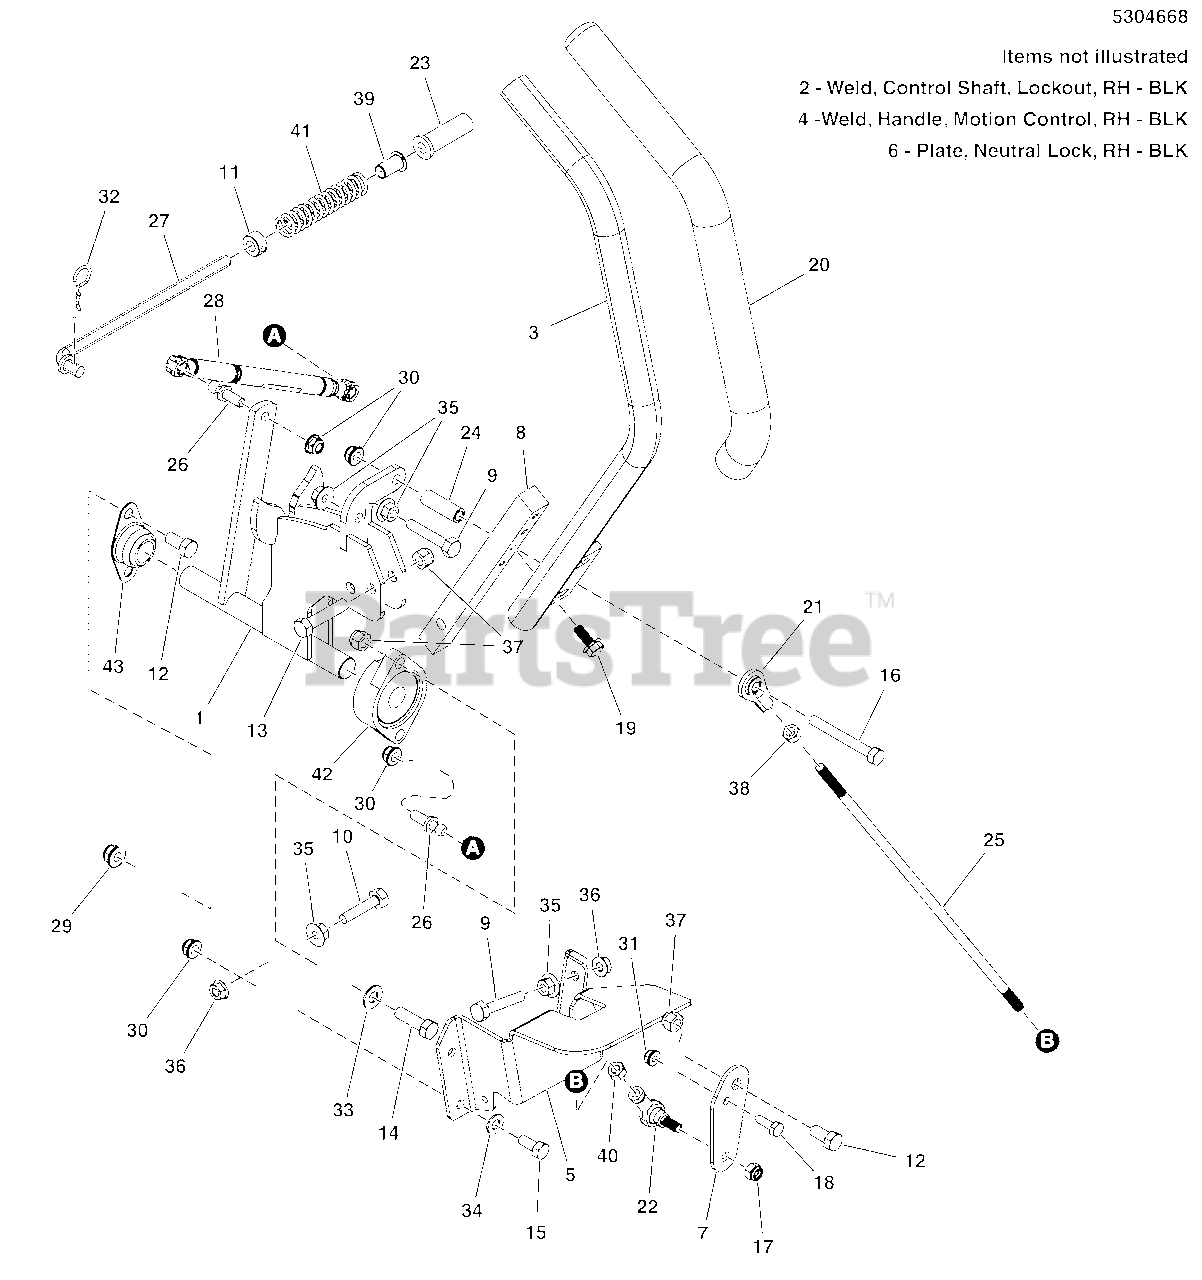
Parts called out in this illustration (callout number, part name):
1	WELD, CONTROL SHAFT, LOCKOUT, LH - BLK
2	WELD, CONTROL SHAFT, LOCKOUT, RH - BLK
3	WELD,HANDLE MOTION CNTRL-19.0,1.0-LH-BLK
4	WELD,HANDLE MOTION CNTRL-19.0,1.0-RH-BLK
5	PLATE, NEUTRAL LOCK, LH - BLK
6	PLATE, NEUTRAL LOCK, RH - BLK
7	PLATE, SPEED CONTROL - BLK
8	MOUNT, CONTROL ARM - BLK
9	BOLT, 5/16-18 X 1-3/4 TFL, GD5 YZ
10	BOLT- 5/16-18 X 1-1/2 GD5 TFL
11	COLLAR, 3/8" Set
12	BOLT, 3/8-16 X 3/4" GD5 CZ
13	BOLT, 3/8-16 X 1-3/4" GD5 CZ
14	BOLT, 3/8-16 X 1-1/4" GD5 CZ
15	BOLT, 5/16-18 X 3/4 GD5
16	BOLT, 5/16-18 X 2-3/4, GD 5, YZ
17	NUT, Hex, Nylon Lock, 5/16-24
18	BOLT, 1/4"-20 X 3/4" GD5 YZ
19	SCREW, 5/16-18X0.750, GR5, WHIZ-LOCK, ZC
20	GRIP, FOAM, 1" ID, 16" LONG
21	BALL JOINT 5/16-24 RH FEMALE STAMPED STL
22	BALL JOINT, 5/16-24 LH FEMALE W/STUD, BR
23	FLANGED BUSHING, 3/8IDX.63ODX.8125FL
24	SPACER, .33 X .50 X 1.50, YZ
25	ROD, HYDRO CONTROL, OUTFRONT
26	10MM BALL STUD, 5/16-18 X 3/4 THDS
27	ROD, NEUTRAL RETURN, CZ
28	DAMPENER, CONTROL,#(P6709/P3610)
29	NUT, 3/8 - 16 HEX NYLOCK FLANGE
30	NUT, 5/16-18 HEX NYLOCK FLANGE NUT
31	NUT, 1/4-20 Hex Nylock Flange
32	3/32 X 1-5/8 HAIR PIN CLIP
33	WASHER, 3/8 SAE
34	WASHER, 5/16" SAE
35	NUT, 5/16-18 HEX SERRATED FLANGE (LARGE)
36	NUT, 5/16-18 HEX SERRATED FLANGE (SMALL)
37	NUT, Hex, Nylon Locking, 3/8-16
38	NUT, Hex, 5/16-24
39	BUSHING, FLANGE 3/8ID X 7/8 LONG
40	NUT, 5/16-24 HEX, LH
41	SPRING, REVERSE RETURN
42	BEARING, FLANGE
43	BEARING, BRONZE FLANGE, 3/4"
